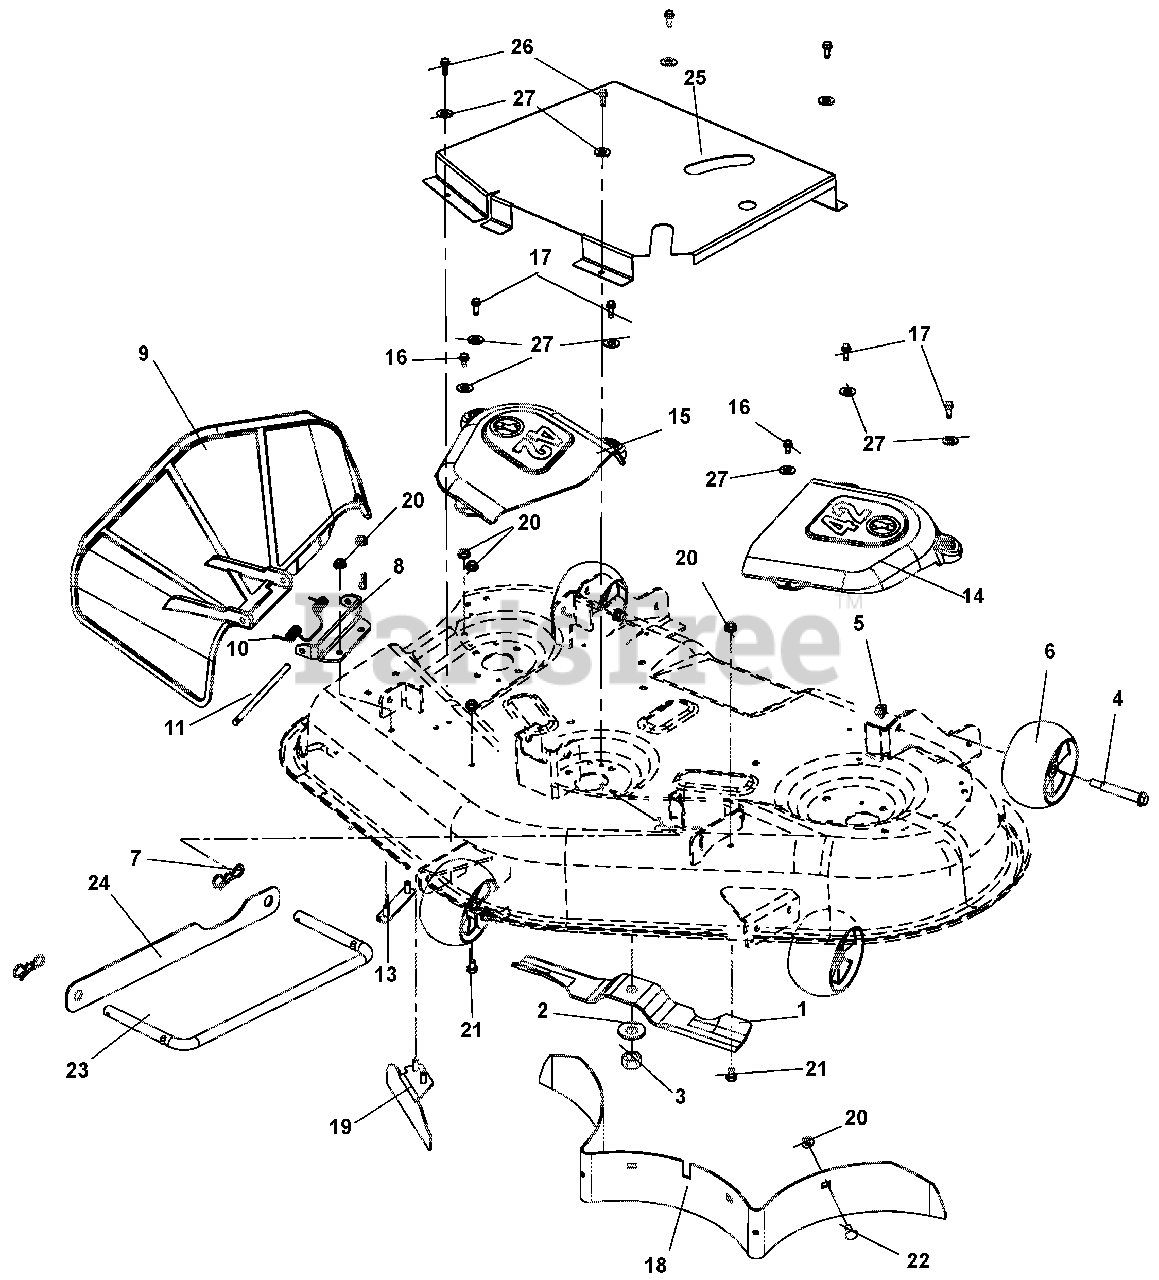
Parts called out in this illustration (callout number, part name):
1	BLADE, MOWER 14.83 (.188 THK)
2	WSHR-BLVL .669X1.535X.138
3	NUT-HEX .62-18 YWZC
4	BLT-SHLDR .38-16X2.50 HWH G5
5	@NUT-LK-TOP-FLG .38-16 YWZC
6	ANTI-SCALP WHEEL - 5X OS
7	PIN,BOW TIE LOCKING .091X1.875
8	BRKT-DISCHARGE CHUTE MOUNT 42"
9	CHUTE, DISCHARGE - MOLDED
10	SPRING-TORSION
11	PIN, 5/16 X 5.80"
12	PIN-HAIR INT .08X.18X1.18 YWZC
13	WMT-DISCHARGE CHUTE MT. STRAP
14	BELT COVER - LH 42"
15	BELT COVER - RH 42"
16	SCR-TAP .25-20X.50 HWH TR YWZ
17	SCR-TAP .25-20X.75 HWH TR YWZ
18	BAFFLE, REAR (42)
19	WLDMT-BAFFLE, DISCHARGE 42"
20	@NUT-LK-TOP-FLG .31-18 YWZC
21	@BLT-HEX .31-18X.50 GR5 YWZC
22	@BLT-RHDSSQNK .31-18X.75 G5YZ
23	WIREFORM, DRAG LINK
24	STRAP, DRAG LINK
25	GUARD, 42" ZOOM/ZT CE BELT
26	SCR-TAP .25-20X.50 LGHWH TR YZ
27	NUT-PUSH .25X.50 O.D.
